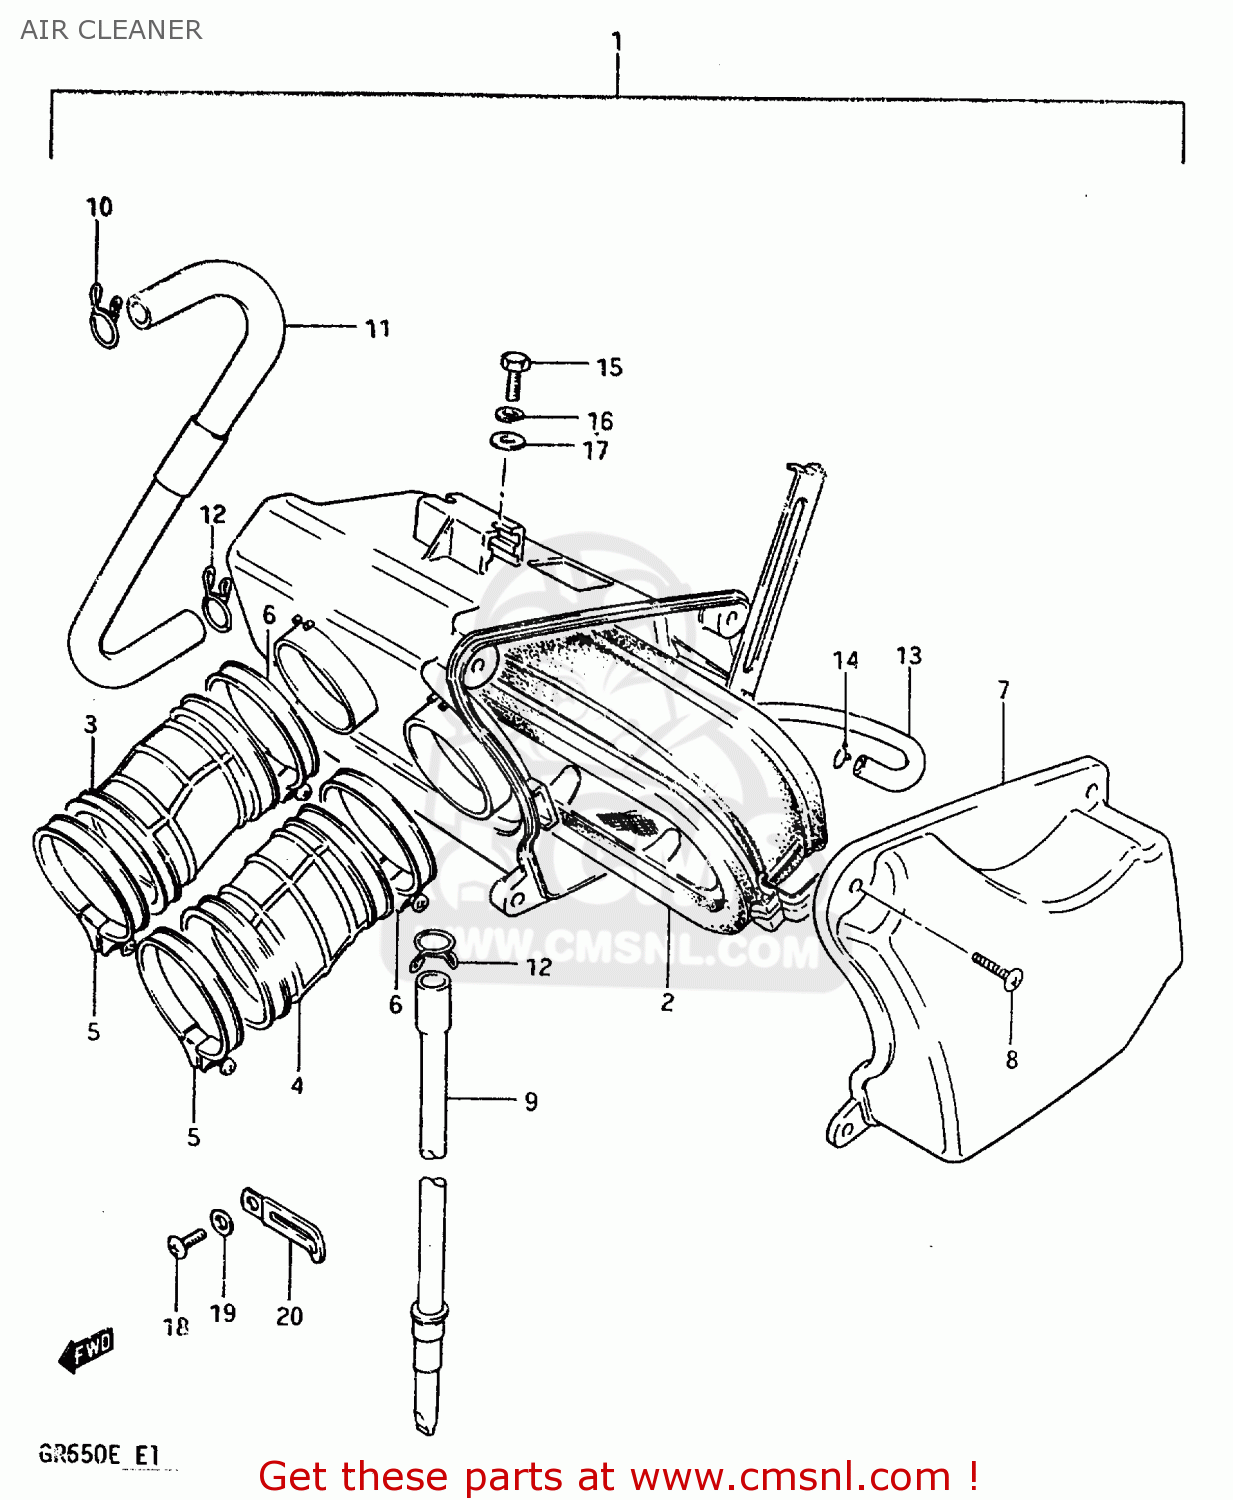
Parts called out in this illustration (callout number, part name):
1	CLEANER ASSEMBLY,AIR
2	FILTER,AIR CLEANER
3	TUBE,AIR CLEANER OUTLET
4	TUBE,AIR CLEANER OUTLET
5	CLAMP
6	CLAMP
7	CAP,AIR CLEANER
8	SCREW
9	DRAIN TUBE
10	CLIP,BREATHER TUBE
11	TUBE,BREATHER
12	CLIP,BREATHER TUBE
13	HOSE, BREATHER (L:300)
14	CLIP
15	BOLT, UPPER
16	LOCK WASHER
17	WASHER
18	SCREW
19	WASHER
20	CLAMP
